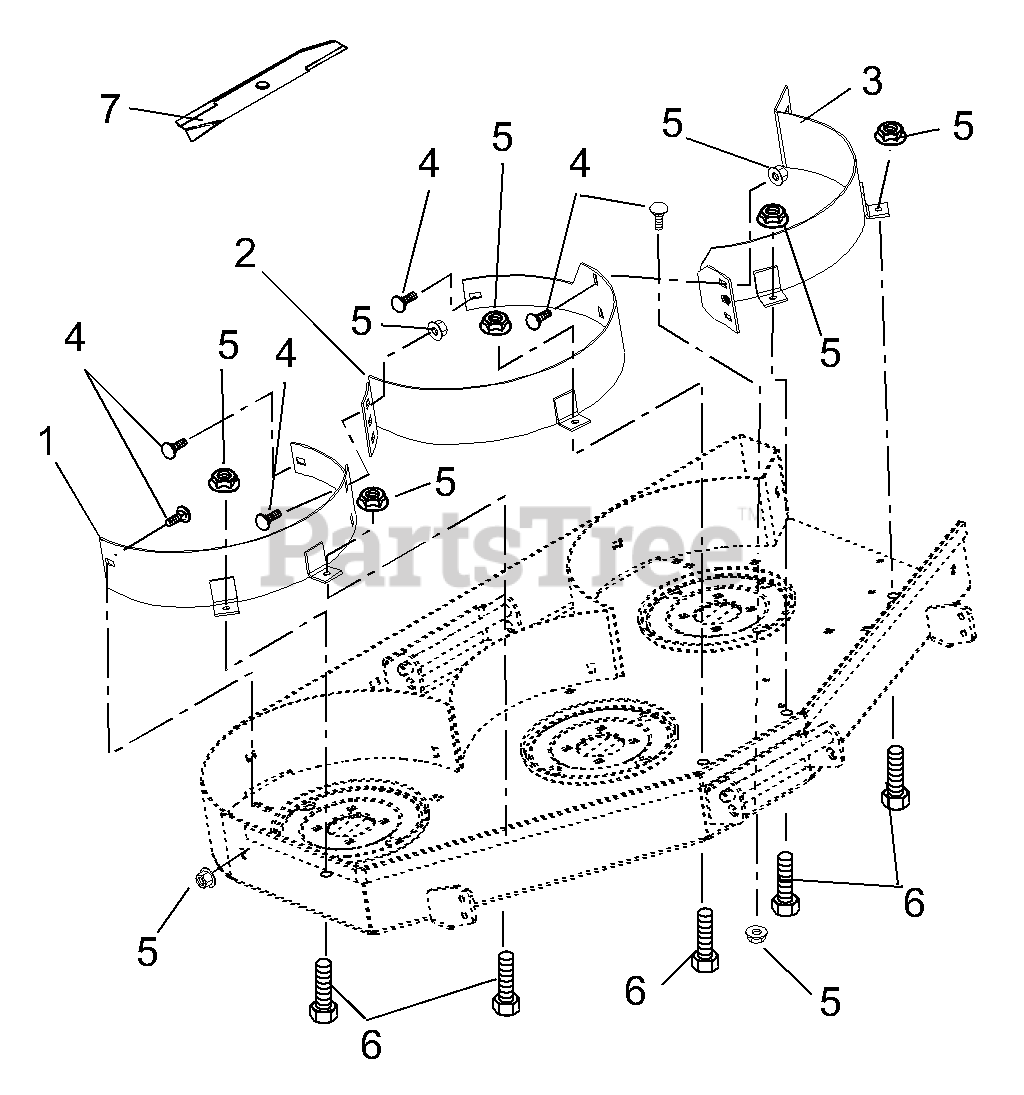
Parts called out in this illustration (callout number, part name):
1	40-Inch Left Hand Mulch Baffle
1	44-Inch Left Hand Mulch Baffle
1	48-Inch Left Hand Mulch Baffle
1	52-Inch Left Hand Mulch Baffle
2	40-Inch Center Mulch Baffle
2	44-Inch Center Mulch Baffle
2	48-Inch Center Mulch Baffle
2	52-Inch Center Mulch Baffle
3	40-Inch Right Hand Mulch Baffle
3	44-Inch Right Hand Mulch Baffle
3	48-Inch Right Hand Mulch Baffle
3	52-Inch Right Hand Mulch Baffle
4	5/16" x 5/8" Round Head Square Neck Bolt
5	5/16" Flange Locknut
6	5/16" x 5/8" Hex Bolt
7	40-Inch Mower Mulching Blade
7	44-Inch Mower Mulching Blade
7	48-Inch Mower Mulching Blade
7	52-Inch Mower Mulching Blade
